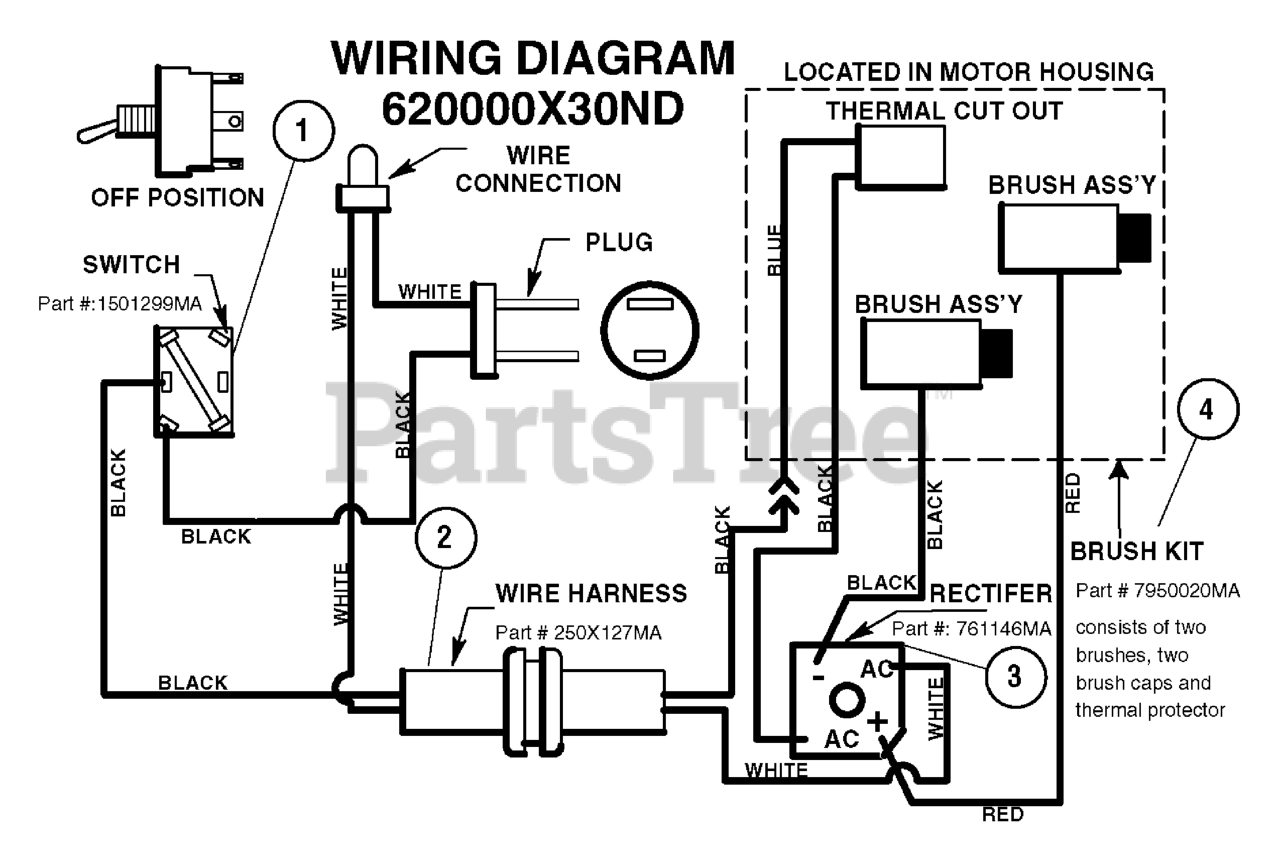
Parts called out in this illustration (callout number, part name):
1	ASSEMBLY, SWITCH BOX
2	WIRE HARNESS
3	RECTIFER
4	BRUSH KIT
